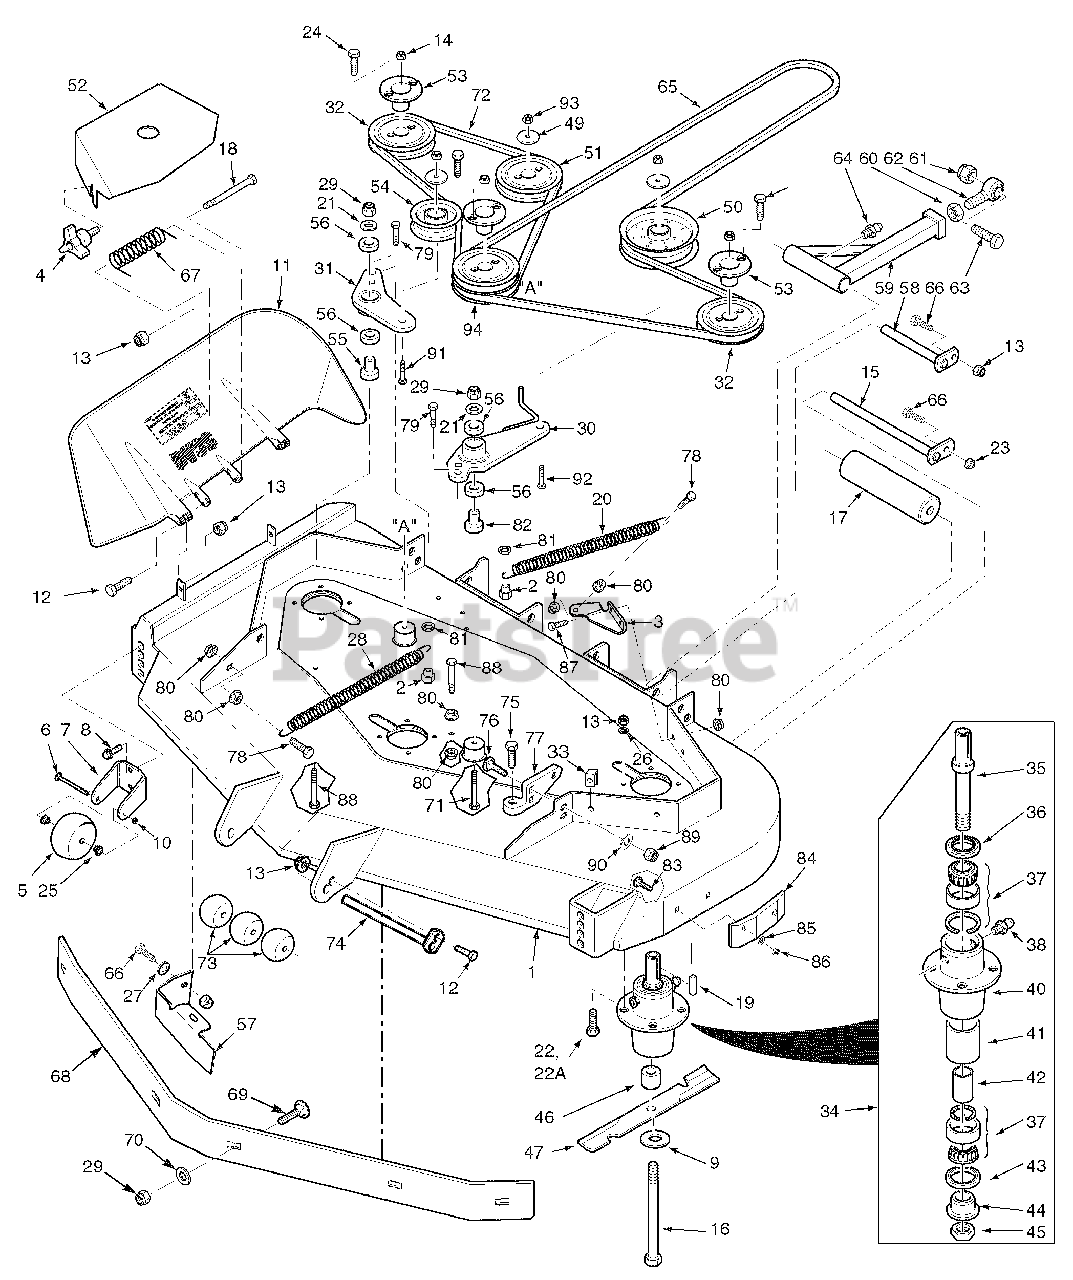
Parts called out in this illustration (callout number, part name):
1	Cutter Deck Velocity Plus
2	Boss, Spring Anchor
3	Bracket, LH Spring Anchor 61V
4	Wing Nut, 3/8-16
5	Anti-Scalp Wheel
6	Bolt, Carriage 3/8-16 x 4"
7	Bracket, Anti-Scalp Wheel
8	Bolt, Serrated Flange 3/8-16 x 1"
9	Flatwasher, 5/8" Hardened
10	Locknut, 3/8-16 Center Lock
11	Discharge Chute
12	Bolt, Hex Head 5/16-18 x 1-1/2", Rear
13	Nut, Elastic Stop 5/16-18
14	Nut, 5/8-11 UNC
15	Shaft, Roller
16	Bolt, Hex Head 5/8-11 x 9-1/2"
17	Roller, Rear
18	Bolt, Hex Head 5/16-18 x 4-3/4"
19	Key, 1/4 x 1/4 x 2"
20	Spring, L.H. Deck Drive
21	Flatwasher, 3/8" - .938 x .391 x .105
22	Bolt, Hex Head 5/16-18 x 1-3/4" Grade 8
23	Nut, Serrated Flange 5/16-18
24	Bolt, Hex Head 1/4-20 x 1" Grade 8
25	Bushing, .376 ID Oilite
26	Lockwasher 5/16"
27	Flatwasher 5/16"
28	Spring, R.H. Deck Drive
29	Nut, Elastic Stop 3/8-16
30	Idler Arm Assembly, LH Drive
31	lder Arm Assembly, RH Drive
32	Pulley, Tapered Bore 6.33" Dia.
33	U-Nut, 3/8-16
34	Spindle Assembly
35	Shaft, Spindle
36	Seal Upper
37	Bearing Assembly
38	Grease Fitting
39	Valve, Grease Relief
40	Housing, Spindle
41	Spacer, Outside
42	Spacer, Inside
43	Seal, Lower
44	Bushing, Bottom
45	Nut, Special 1-1/16 - 18
46	Spacer, Spindle
47	Cutter Blade 21"
48	Pulley, Double Groove 6.33" Dia.
49	Dust Shield
50	Idler Pulley, 5" Dia.
51	Idler Pulley, 5" Dia.
52	Belt Cover
53	Hub, Tapered 1-1/8" Bore
54	Idler Pulley, 3-1/2" Dia.
55	Pivot, Idler
56	Bearing
57	Turbo Baffle, Bolt On
58	Push Arm Shaft
59	Push Arm
60	Nut, 5/8-18 UNF
61	Nut, Elastic Stop 5/8-11
62	Rod End, 5/8 Male RH Thread
63	Bolt, Hex Head 5/8-11 x 4-1/2"
64	Grease Fitting, 90 Degree
65	Belt, Deck Drive 61V
66	Bolt, Hex Head 5/16-18 x 1"
67	Spring, Discharge Chute
68	Baffle Weldment, 61V
69	Bolt, Carriage 3/8-16 x 1"
70	Flatwasher, 3/8-.391 x .938 x .105
71	Bolt, Hex Head 3/8-16 X 3-1/2"
72	Belt, Deck Drive RH
73	Wheel, Anti Scalp
74	Roller Shaft
75	Bolt, Special
76	Bolt, Carriage 7/16-14 x 1-1/4"
77	Lever Assy., Deck Level
78	Bolt, Hex Head 3/8-16 x 1-1/2" Gr.8
79	Bolt, Hex Head 3/8-16 x 1"
80	Nut, Serrated Flange 3/8-16
81	Lockwasher, 5/16"
82	Pivot, Idler Short
83	Bolt, Carr. 5/16-18 x 3/4"
84	Wear Pad
85	Flatwsher, 5/16-.344 x .688 x .065
86	Nut, Center Lock 5/16"
87	Bolt, Hex Head 3/8-16 x 1"
88	Bolt, Hex Head 3/8-16 x 2-1/2"
89	Nut, Elastic Stop 7/16-14
90	Flatwasher, 7/16-.500 x 1.250 x .083
91	Bolt, Hex Head 3/8-16 x 2-1/4"
92	Bolt, Hex Head 3/8-16 x 3"
93	Nut, Elastic Stop 3/8-16
94	Pulley, Double Groove 6.33 Dia.
